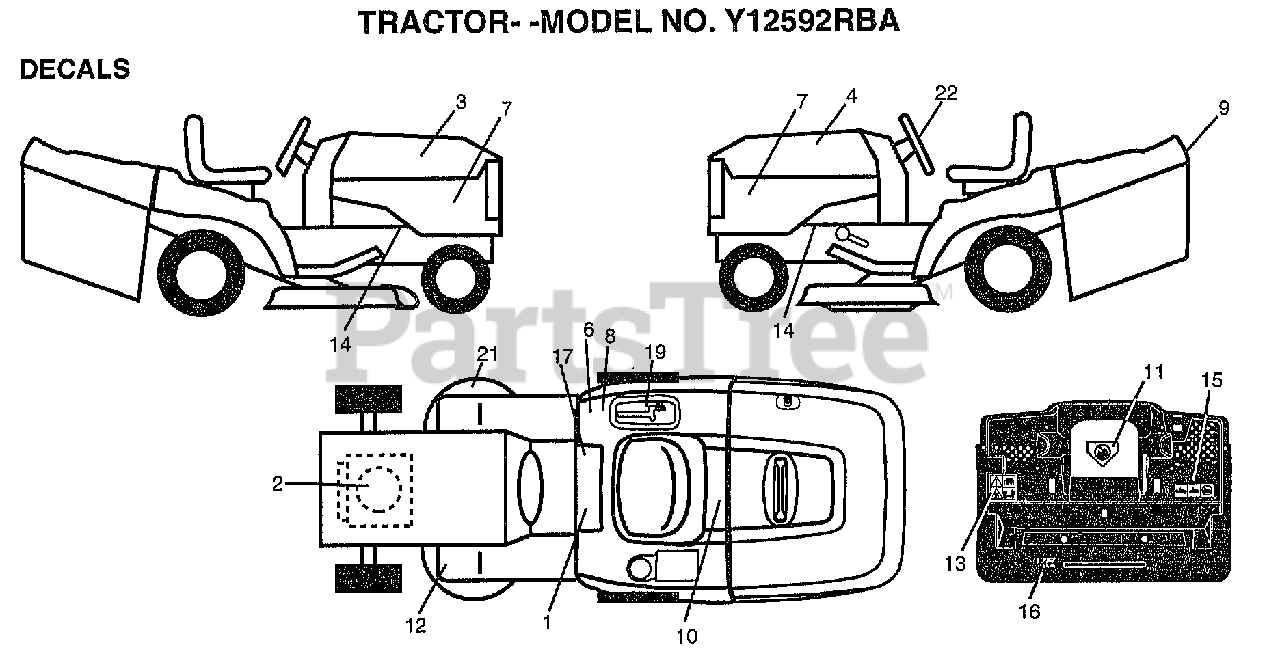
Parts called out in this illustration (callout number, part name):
1	DECAL.READ.O.MANU
2	DECAL.ENG.B&S
3	DECAL.HD.RH.
4	DECAL.HD.LH.
7	DECAL, PANEL
8	DECAL.EURO.ST.CE.
10	DECAL.BATRY.3-3908
11	DECAL.DANGER.CUTF
12	DECAL-BRAKE/CLUTC
13	DECAL.WARNING.BACKPLATE.CRD
14	"DECAL CHASSIS,HOT"
15	DECAL, OPER BAG
16	DECAL.DRAWBAR.LDL
17	DECAL BRAK PARK
19	DECAL.CONSOLE.6SP.CRD
21	DECAL.DECK.HEX.BELT
22	DECAL.INS.STRG.WH
